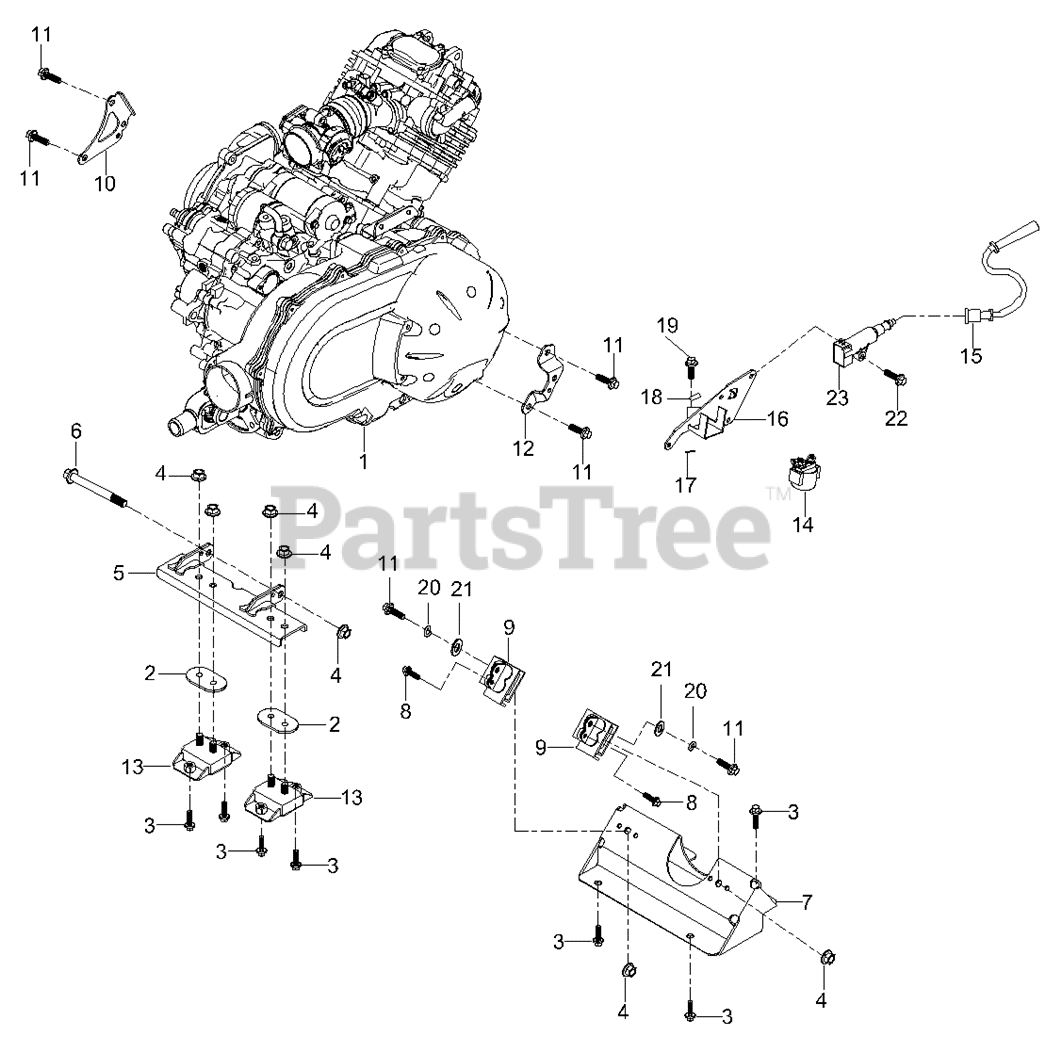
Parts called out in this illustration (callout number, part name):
1	COMPLETE ENGINE - 750
1	COMPLETE ENGINE - 550
2	ENGINE DAMPENING WASHER
3	HEX BOLT & WASHER ASSEMBLY
4	LOCK NUT M10X1.25
5	ENGINE MOUNTING BRACKET ASM
6	HEX BOLT (M10x1.25x180)
7	ENGINE MOUNTING BRACKET II
8	HEXAGON FLANGE BOLT M6X16
9	ENGINE MOUNTING REAR ASSEMBLY
10	ENGINE MOUNT BRACKET (REAR RH)
11	HEXAGON FLANGE BOLT M8X20
12	ENGINE MOUNT BRACKET (REAR LH)
13	ENGINE MOUNTING DAMPENER
14	STARTER RELAY
15	IGNITION CABLE (750cc Engine)
15	IGNITION CABLE (550cc Engine)
16	IGNITION COIL MOUNT
17	FOAM CUSHION
18	STARTER RELAY LATCH
19	CROSS PLATE HEAD SCREW M6X12
20	SPRING WASHER-8
22	HEXAGON FLANGE BOLT M6X40
23	IGNITION COIL
